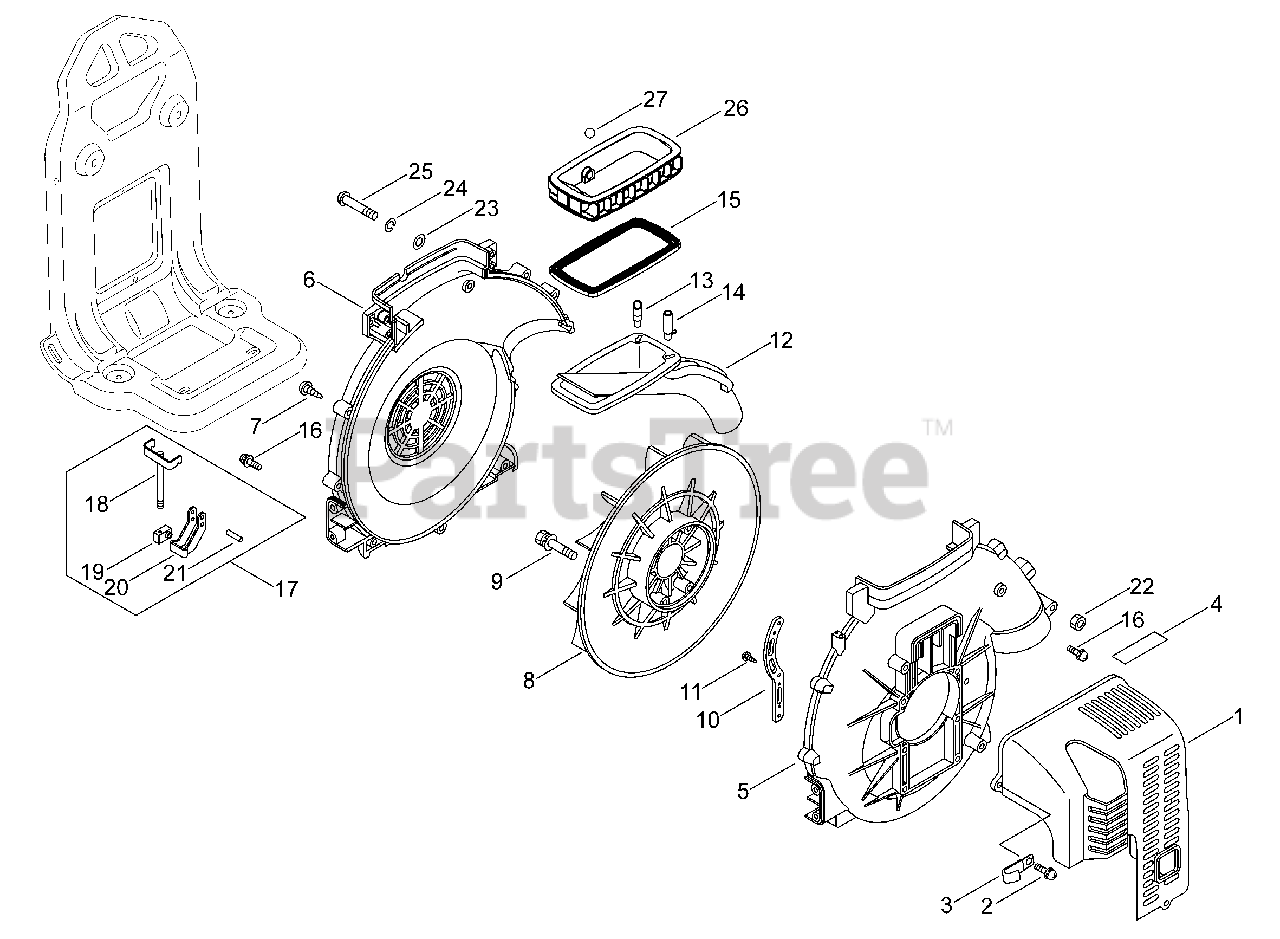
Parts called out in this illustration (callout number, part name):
1	COVER, ENGINE
2	SCREW 5×20
4	LABEL, CAUTION - HOT
5	CASE, FAN
6	COVER, FAN
7	SCREW 5×25 SUS
9	BOLT 5×35
10	PLATE, ENGINE
11	SCREW 4×10
12	PIPE, DUST OUTLET
13	GUIDE, LOWER TANK AIR
14	GUIDE, AIR
15	GASKET, LOWER TANK
16	SCREW 5×14 SUS
17	RETAINER ASSY, CHEMICAL TANK
19	CONNECTOR, BRACKET
20	RETAINER, CHEMICAL TANK
22	NUT, LOCK M5
23	WASHER SS 5 MM
24	WASHER, SPRING 5 SUS
26	TANK, LOWER
